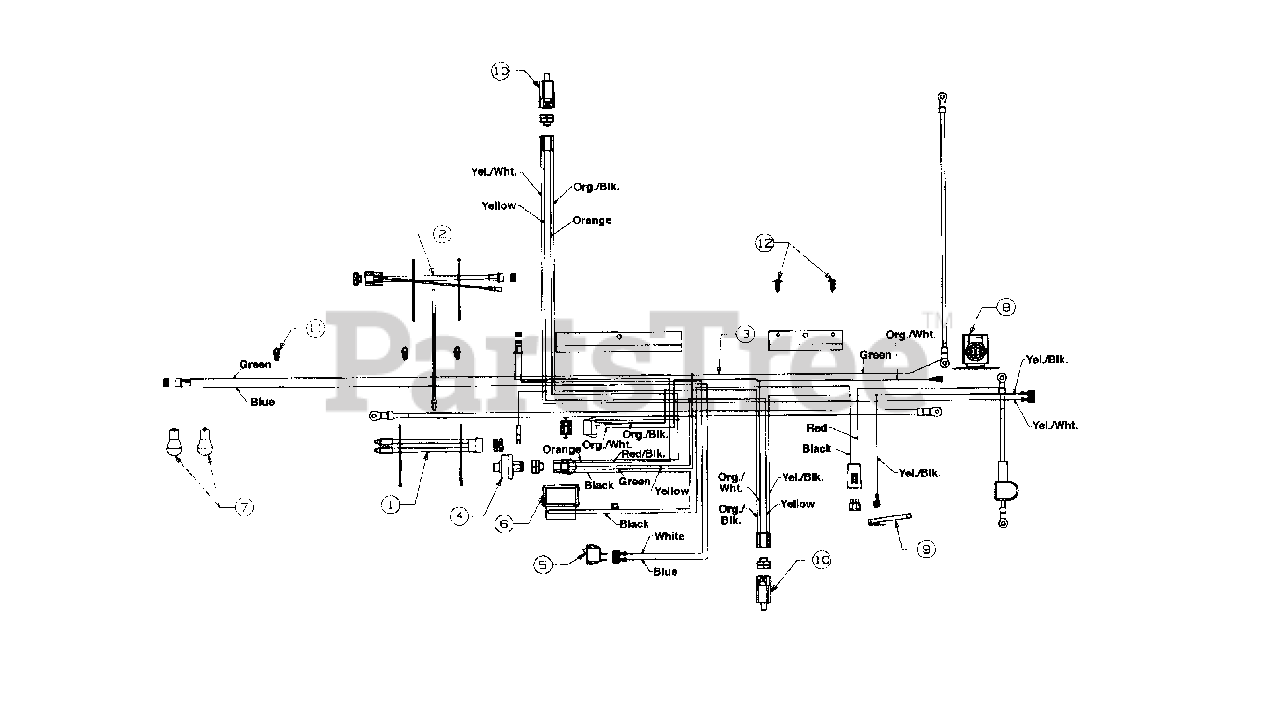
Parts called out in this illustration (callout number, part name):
1	Ratchet
2	Safety Switch
3	Solenoid
4	Bulb (Headlight)
5	Ammeter
6	Light Switch
7	Ignition Switch
8	Wire Harness
9	Wire Harness Adapter
10	Wire Harness (Monitor)
